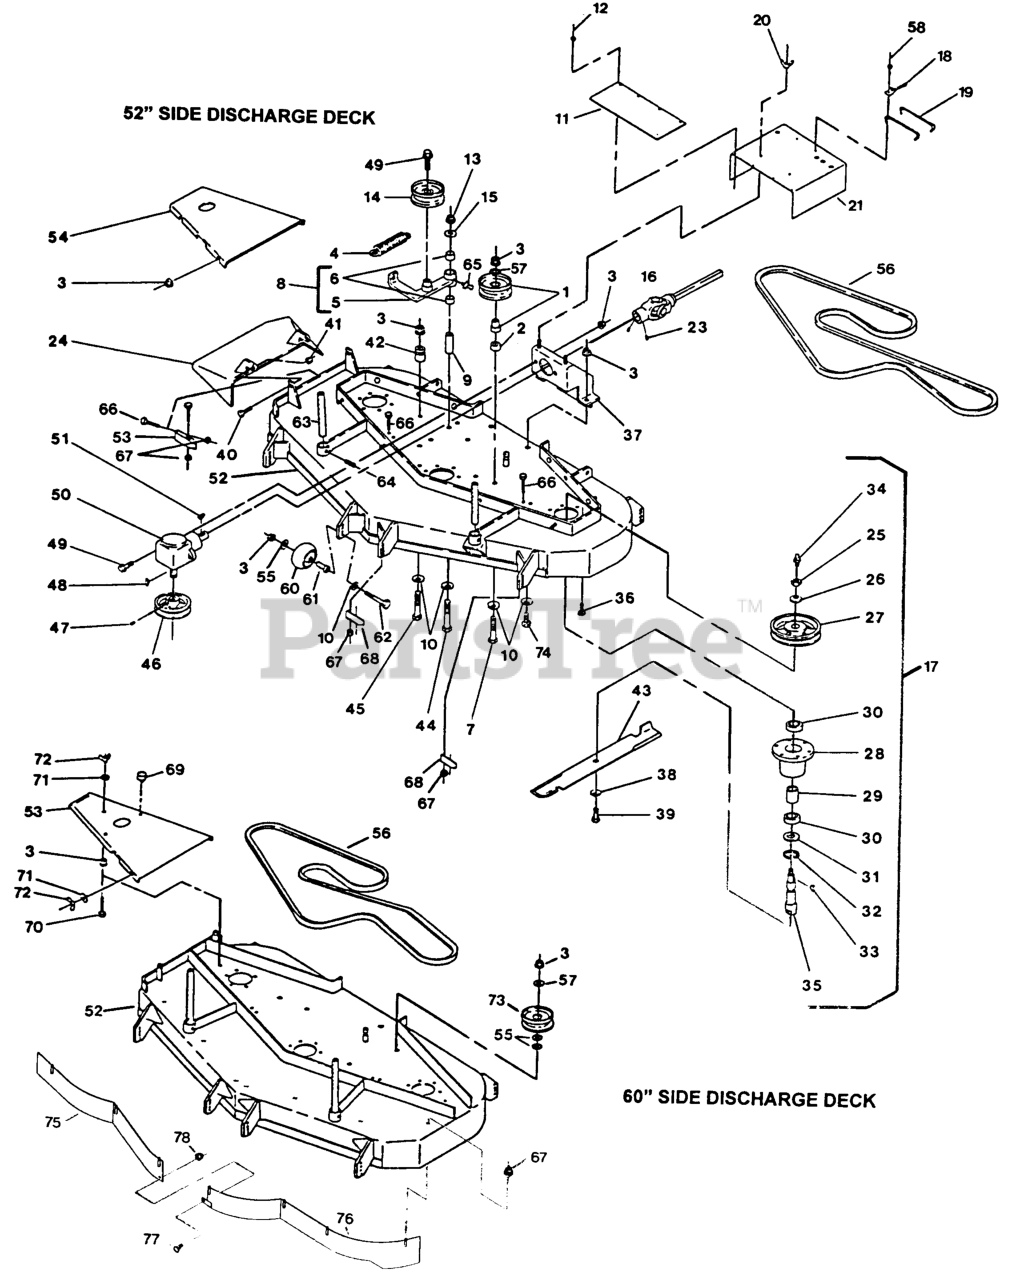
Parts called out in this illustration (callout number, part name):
1	KIT,48 RH IDLER/BUS
4	SPRING,EXTENSION
6	SLEEVE-BEARING
9	BUSHING
11	SHIELD,PTO GUARD
12	RIVET-POP
14	IDLER,PULLEY
17	CH-52&60 OUTER CUTTR
18	CLIP-DECK, HOLD UP ROD
20	WINGNUT-NYLOCK
22	PTO SHAFT,SHAFT HALF PNT
24	WLD,CHUTE DISCHARGE
26	WASHER-SPRING
27	SHEAVE,BLADE DRIVE
29	SPACER,BEARING
31	SEAL,MECHANICAL DUST
32	RING,SNAP WLDS N5000-244
35	SPINDLE-OUTER BLADE
36	SCRW,TPTTE HH
37	WLD,GEARBOX SUPPORT
38	WASHER-SPRING
42	ANCHOR-SPRING PLTD
47	SCREW-SET
53	WLD,BAFFLE DISCHARGE
58	Pop Rivet, Steel 3/16 X .250
60	ROLLER-SCALP, ANTI
61	BUSHING-ROLLER
63	ROD,DECK SUPPORT
72	NUT-WING
73	IDLER,PULLEY
75	WLD,RH BAFFLE
77	BOLT-CARR
